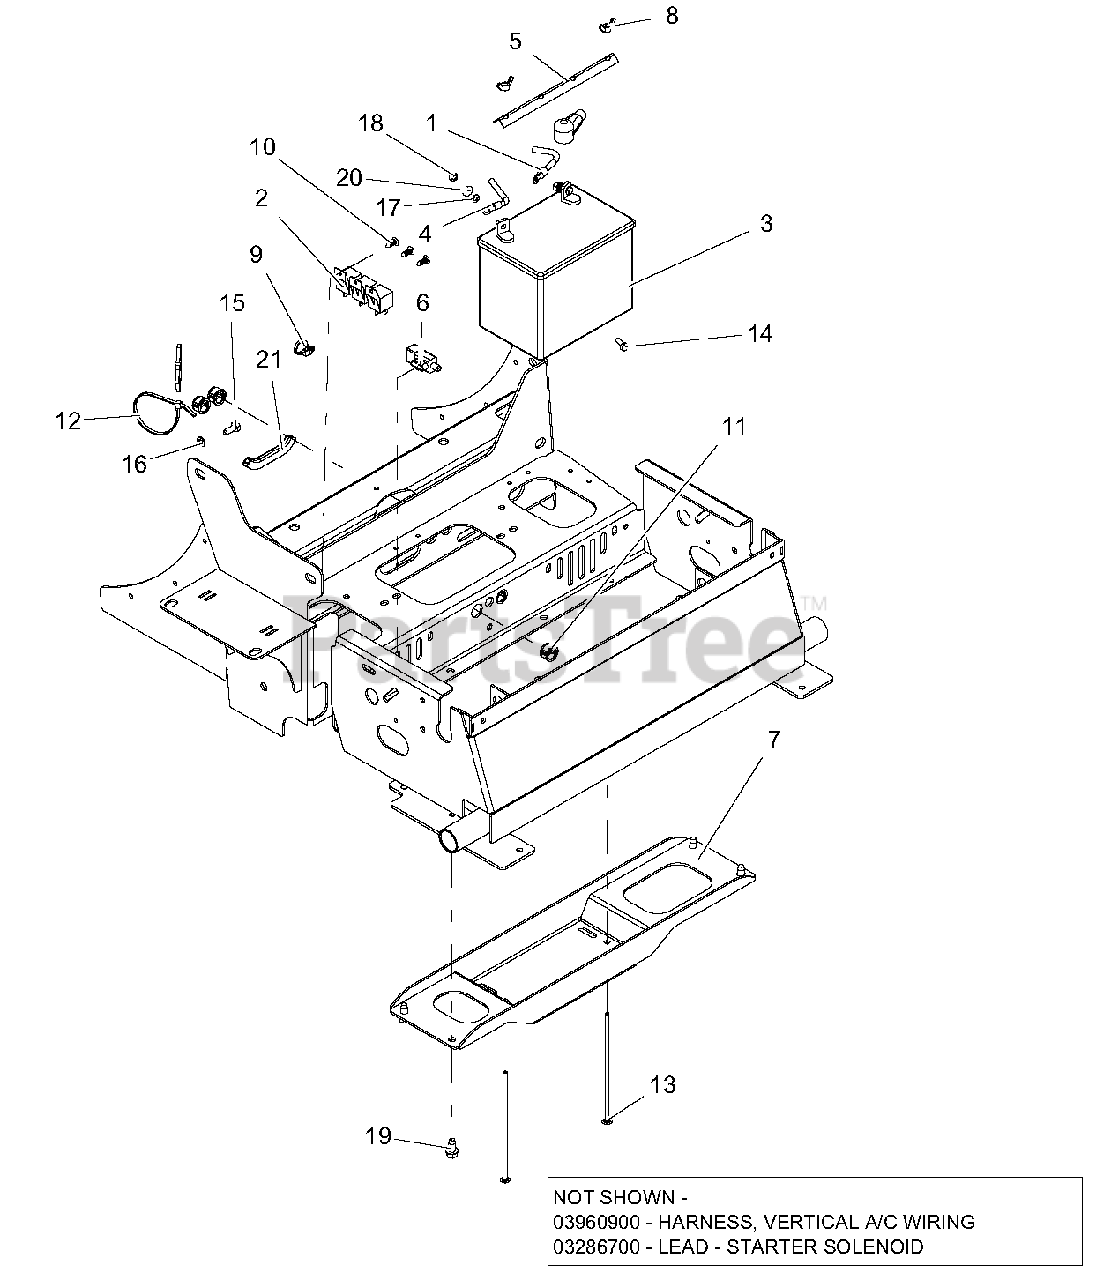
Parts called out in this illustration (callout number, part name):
1	CABLE, POS BATT W/ BOOTS 6 X 35
2	RELAY, SEALED W/DIODE
3	BATTERY,
4	CABLE, NEGATIVE BATTERY 35.00"
5	HOLD DOWN - BLK
6	SWITCH, SNAP IN -N.O./N.O
7	TRAY, BATTERY-RED
8	NUT-LOCKING WING 1/4-20
9	CABLE TIE W/ TREE (.25 HOLE)
10	RIVET, .25 NYLON PANEL
11	BUSH, PANEL SNAP .687X.875X.56
12	CABLE, TIE 5.50 LG
13	@BLT-RDHDSQNK .25-20X7.50 G2 YWZC
14	BLT-HEX .25-20X.75 GR5 YWZC
15	@BLT-HEX M8-1.25X20 YWZC
16	@WSHR-LK .31X.078 REG YWZC
17	@WSHR-LK .25X.062 REG YWZC
18	NUT-HEX .25-20 YWZC
19	SCR-TAP .38-16X.75 HWH TR YWZ
20	@WSHR-FL-STL.281X.62X.065 YWZC
21	STRIP, COWL - 1.50 LG
